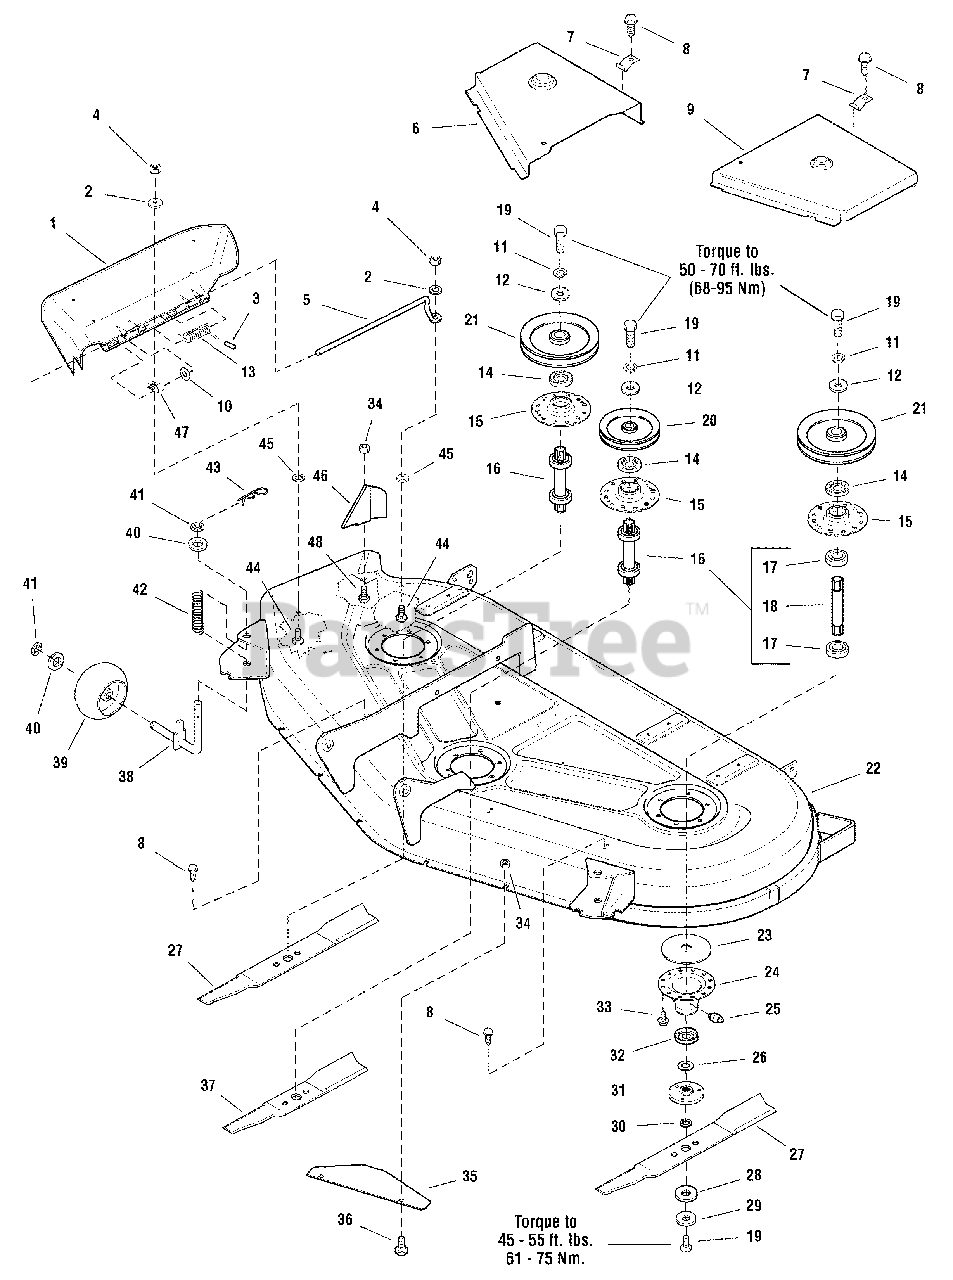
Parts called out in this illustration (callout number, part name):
1	DEFLECTOR, Plastic
2	WASHER, Plain, 1/4
3	CAP, Spring End
4	NUT, Hex, Lock ESNA, 1/4-20, Black
5	ROD, Deflector, Front
6	COVER, Arbor, RH (Red)
7	CLIP, Spring
8	SCREW Hex Head, Taptite, 1/4-20 x 3/8
9	COVER, Arbor, LH (Red)
10	WASHER, Plain, 5/16
11	WASHER, Lock, 7/16
12	WASHER, 7/16
13	SPRING, Torsion
14	SHIELD
15	HOUSING, Arbor, Top
16	ARBOR SHAFT & BEARING ASSEMBLY (Includes Ref. Nos. 17 & 18)
17	BEARING, Ball, 3/4 x 1-3/4 x 5/8
18	ARBOR SHAFT
19	CAPSCREW, Hex Head, 7/16-14 x 1-1/4, G8
20	PULLEY, Assembly, Center
21	PULLEY, Assembly, Out Side
22	HOUSING ASSEMBLY, 54" Legacy XL (Red)
23	GASKET, Foam
24	ASSEMBLY, Housing, Bottom (Includes Ref. No. 25)
25	FITTING, Lube
26	WASHER, Shim
27	BLADE, Mower, 20-1/2
28	WASHER, Spline
29	WASHER, Spring
30	RING, Self Locking
31	ADAPTER, Blade
32	SHIELD, Grass
33	CAPSCREW, Hex Head, Taptite, 5/16-18x 3/4, Black
34	NUT, Hex Keps Conical Washer, 5/16-18
35	BAFFLE, Front, Anti-Blowout
36	CARRIAGE BOLT, 5/16-18 x 3/4
37	BLADE, Mower, 16
38	SPINDLE & STOP ASSEMBLY
39	WHEEL, Gauge
40	WASHER, Plain, 5/8
41	RING, Clip
42	SPRING, Compression
43	CLIP, Hairpin
44	CARRIAGE BOLT, 1/4-20 x 1, Black
45	NUT, Push
46	BAFFLE, Discharge
47	CLAMP, Wire
48	CAPSCREW, Hex Head, 5/16-18 x 5/8, Black
